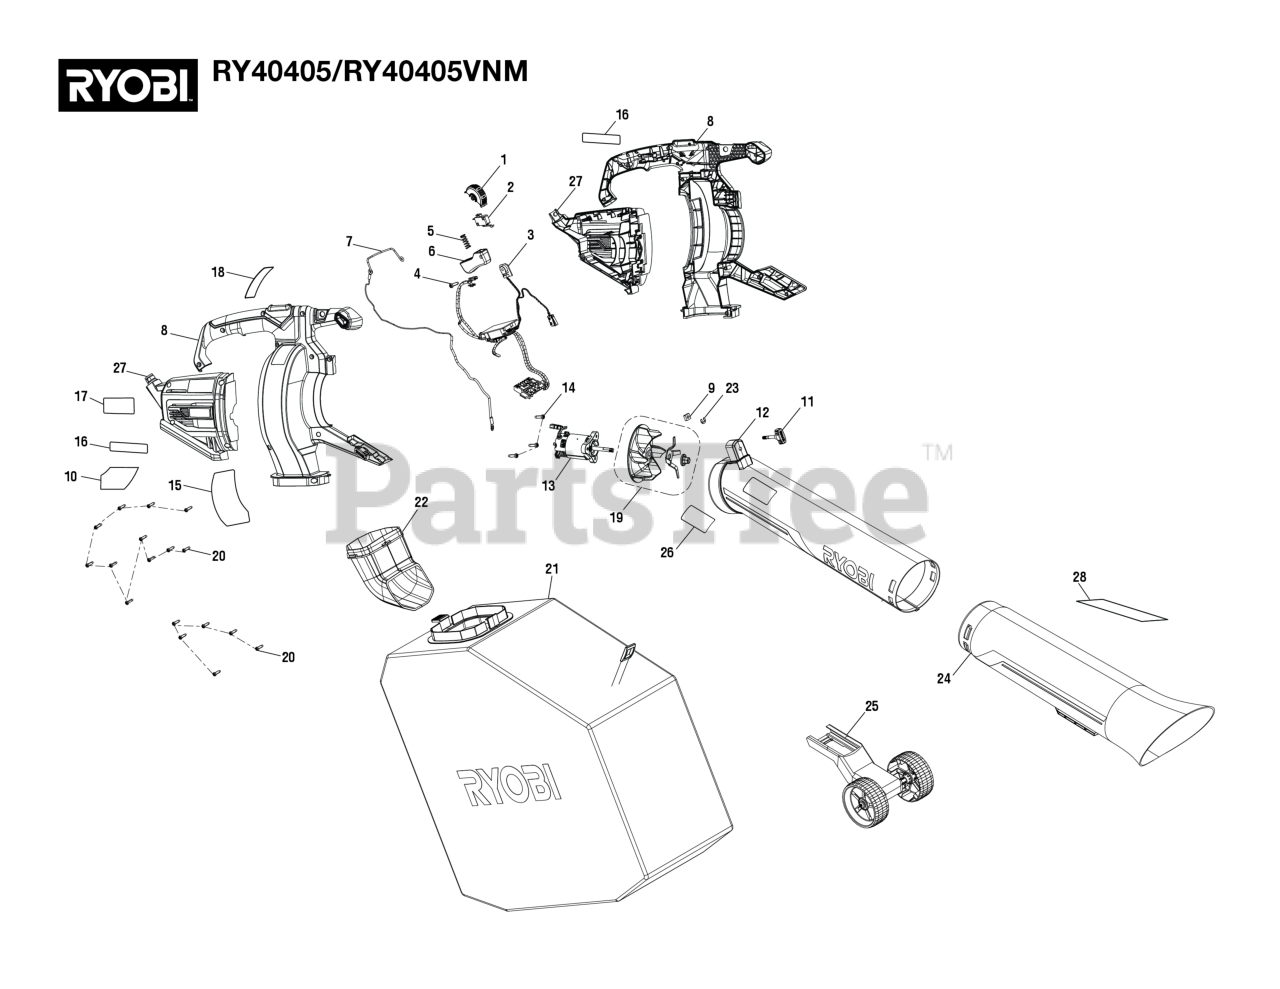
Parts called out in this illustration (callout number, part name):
1	Dial Lever Assembly
2	Switch (Micro)
3	Motor Controller & Battery Holder Assembly
4	SCREW, CH M3 PH B\L=6MM
5	Compression Spring
7	Hand Wire Assembly.
8	Handle Housing Assembly (Inc. Key Nos. 10, 15 & 18)
9	Square Nut (M5)
10	Caution Label
12	Upper Tube Assembly (Inc. Key No. 26)
13	Motor Assembly
14	Screw (T25 x 12 mm, Flange Hd.)
15	Warning Label (French & Spanish)
16	Logo Label
17	Data Label
18	Warning Icon Label
19	Blade Assembly
20	Screw (M4 x 14 mm, T15 Torx Pan Hd.))
21	Bag Assembly
22	Leaf Chute
23	Retaining Ring
24	Lower Tube Assembly (Inc. Key No. 28)
25	Wheel Assembly
26	Start Label
27	Motor Housing Assembly (Inc. Key Nos. 16-17)
28	Vac Attack Label
